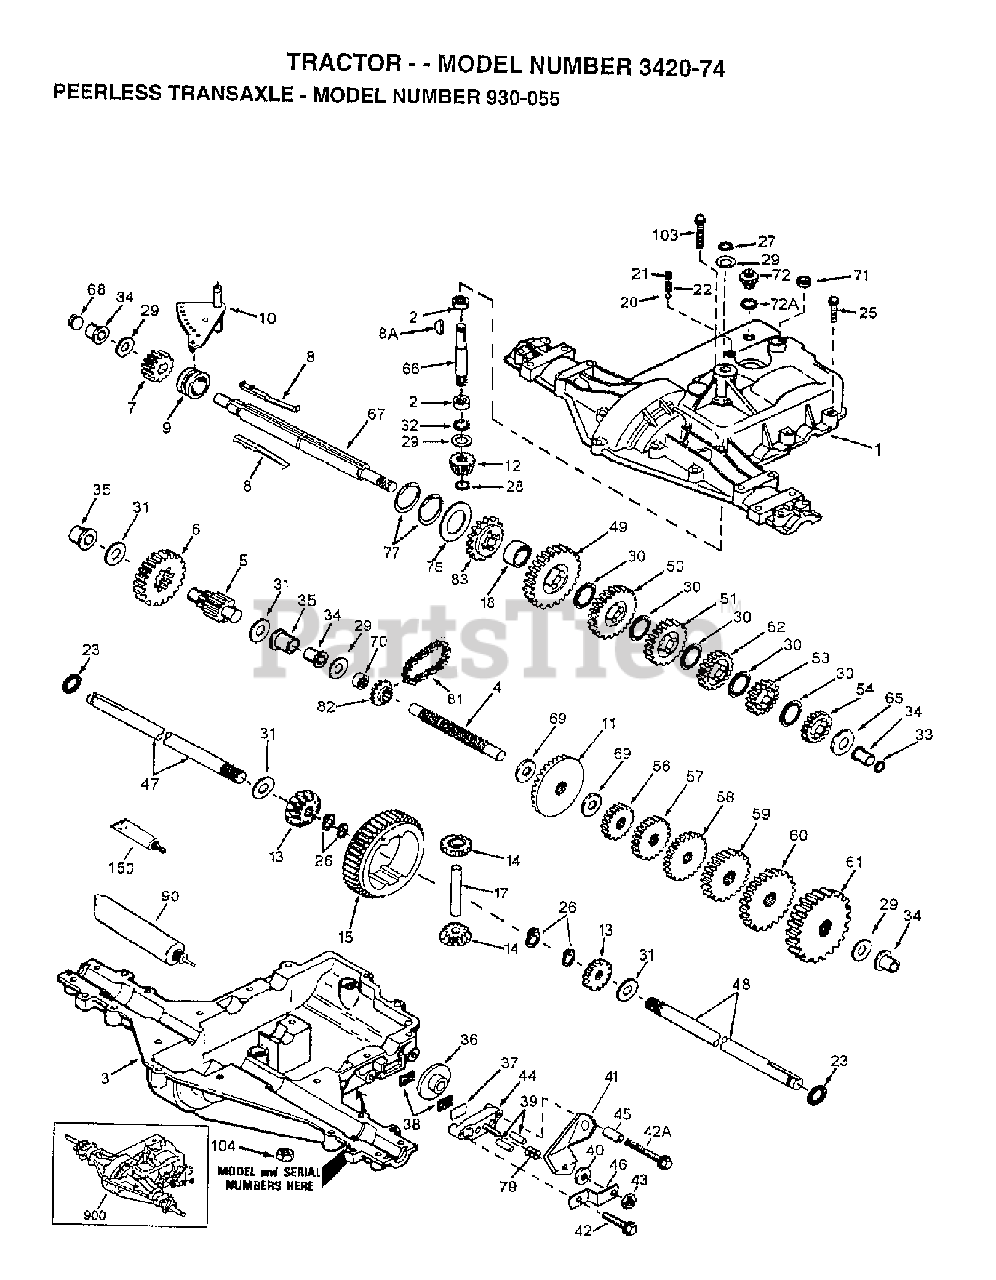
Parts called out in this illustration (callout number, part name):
1	Poulan TBD
3	Poulan TBD
5	Poulan TBD
8	Poulan TBD
12	Poulan TBD
34	Poulan TBD
35	Poulan TBD
51	Poulan TBD
52	Poulan TBD
53	Poulan TBD
58	Poulan TBD
59	Poulan TBD
60	Poulan TBD
67	Poulan TBD
68	Poulan TBD
90	Poulan TBD
